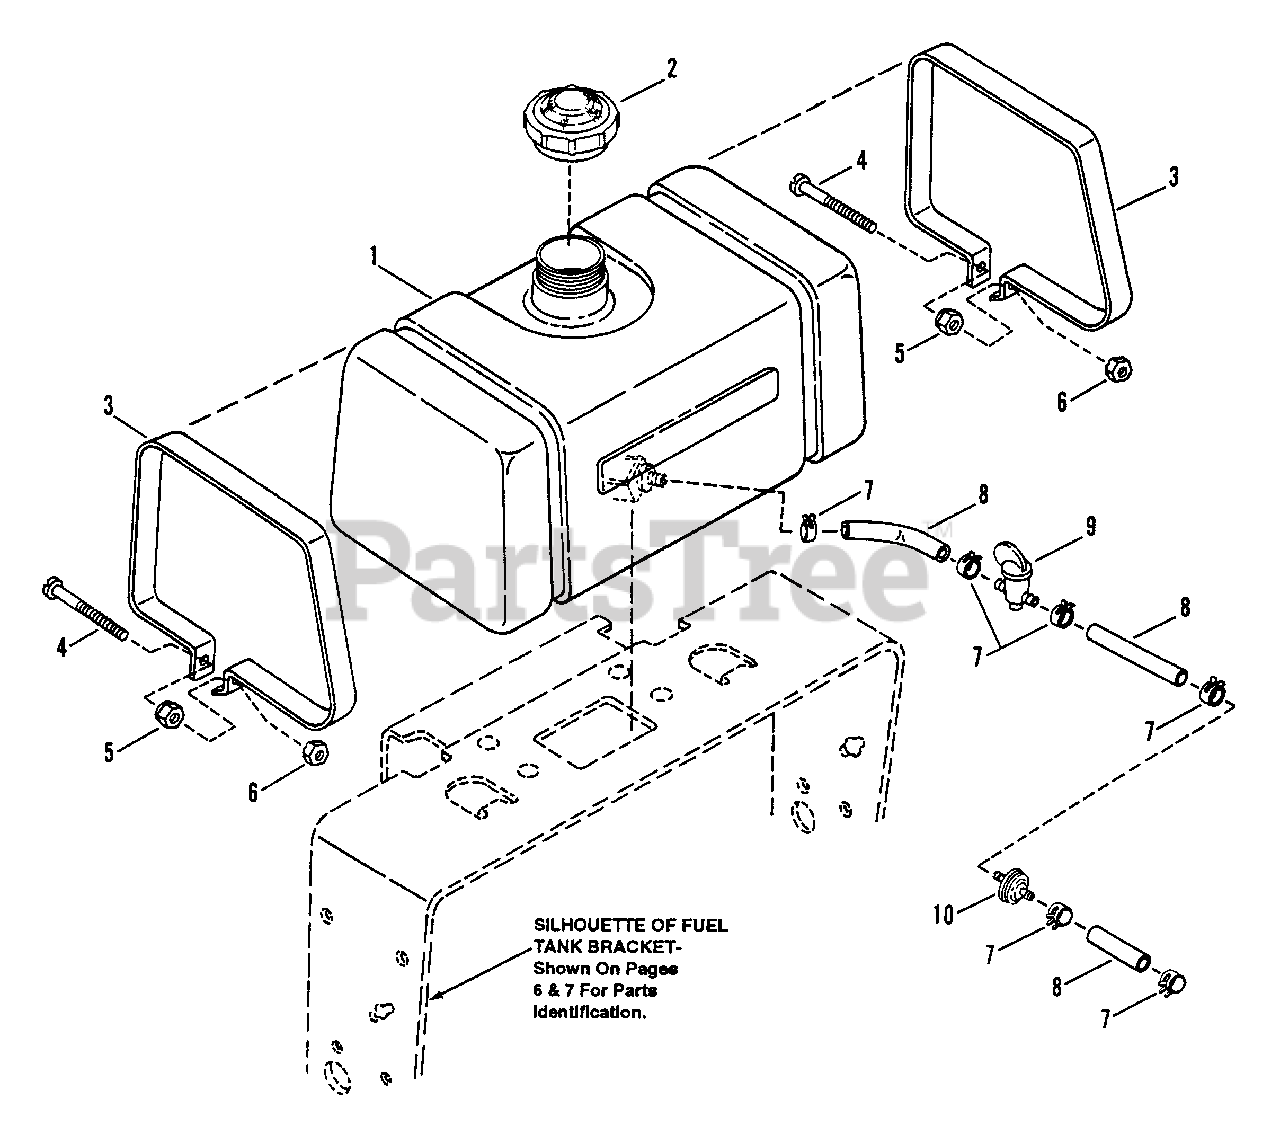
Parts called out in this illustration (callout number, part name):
1	TANK, Fuel
2	CAP, Fuel
3	STRAP, Fuel Tank
4	SCREW, #10-24 x 2-1/2" Machine Head Phillips
5	NUT, 010-24 Keps
6	NUT, #10-24 Nyloc
7	CLAMP, Fuel Hose
8	HOSE, Fuel, 10" Long
9	VALVE, Fuel Shut-Off
10	FILTER, Fuel, In-Line (Kawasaki)
